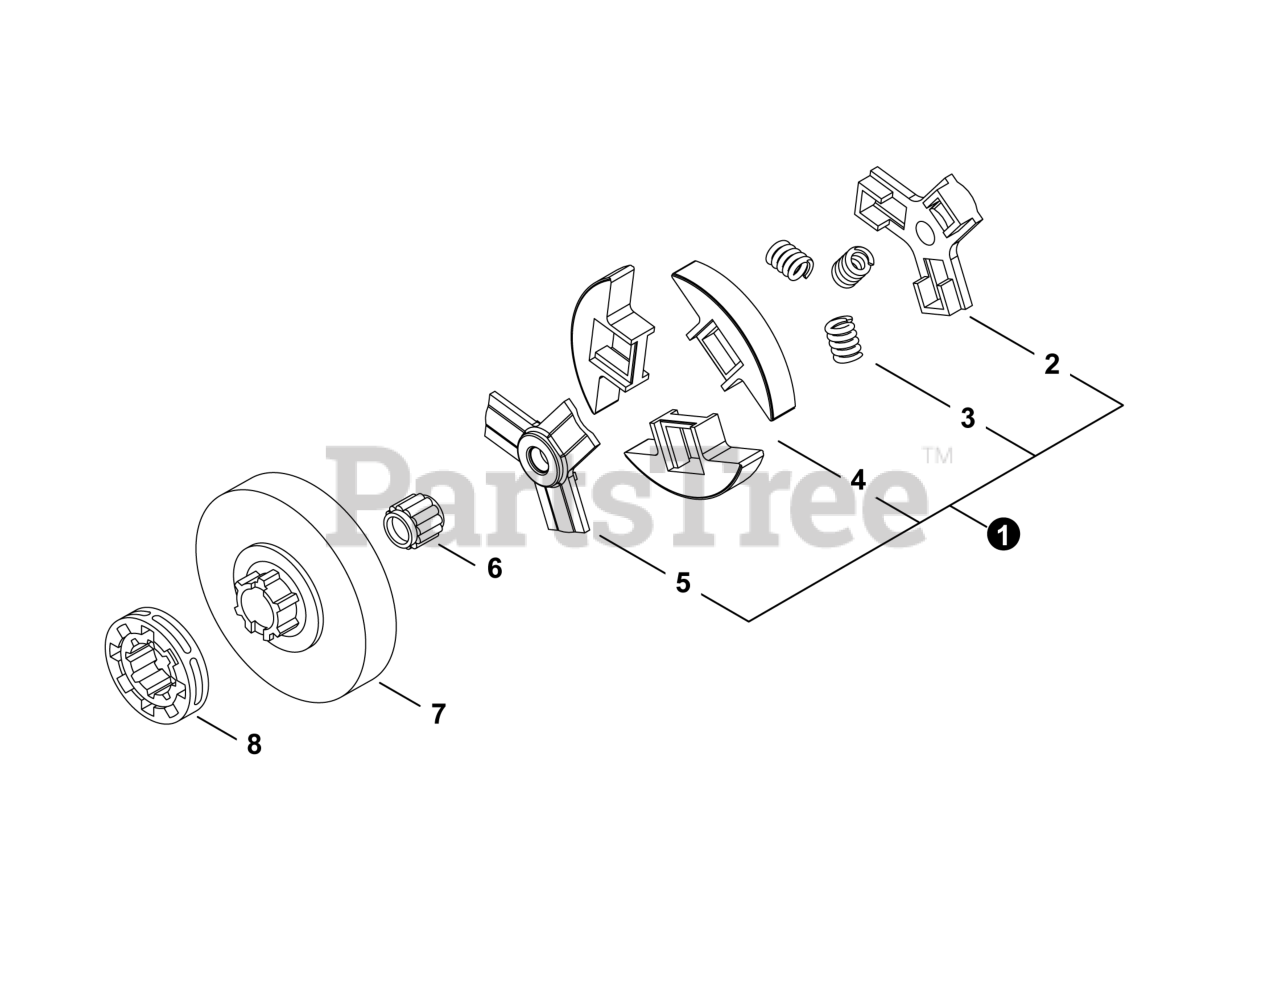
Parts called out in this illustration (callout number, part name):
1	CLUTCH ASSY
2	HUB, CLUTCH
3	SPRING, CLUTCH
4	SHOE, CLUTCH
5	HUB, CLUTCH
6	BEARING, NEEDLE
7	DRUM, CLUTCH
8	SPROCKET, RIM 3/8"×7T
